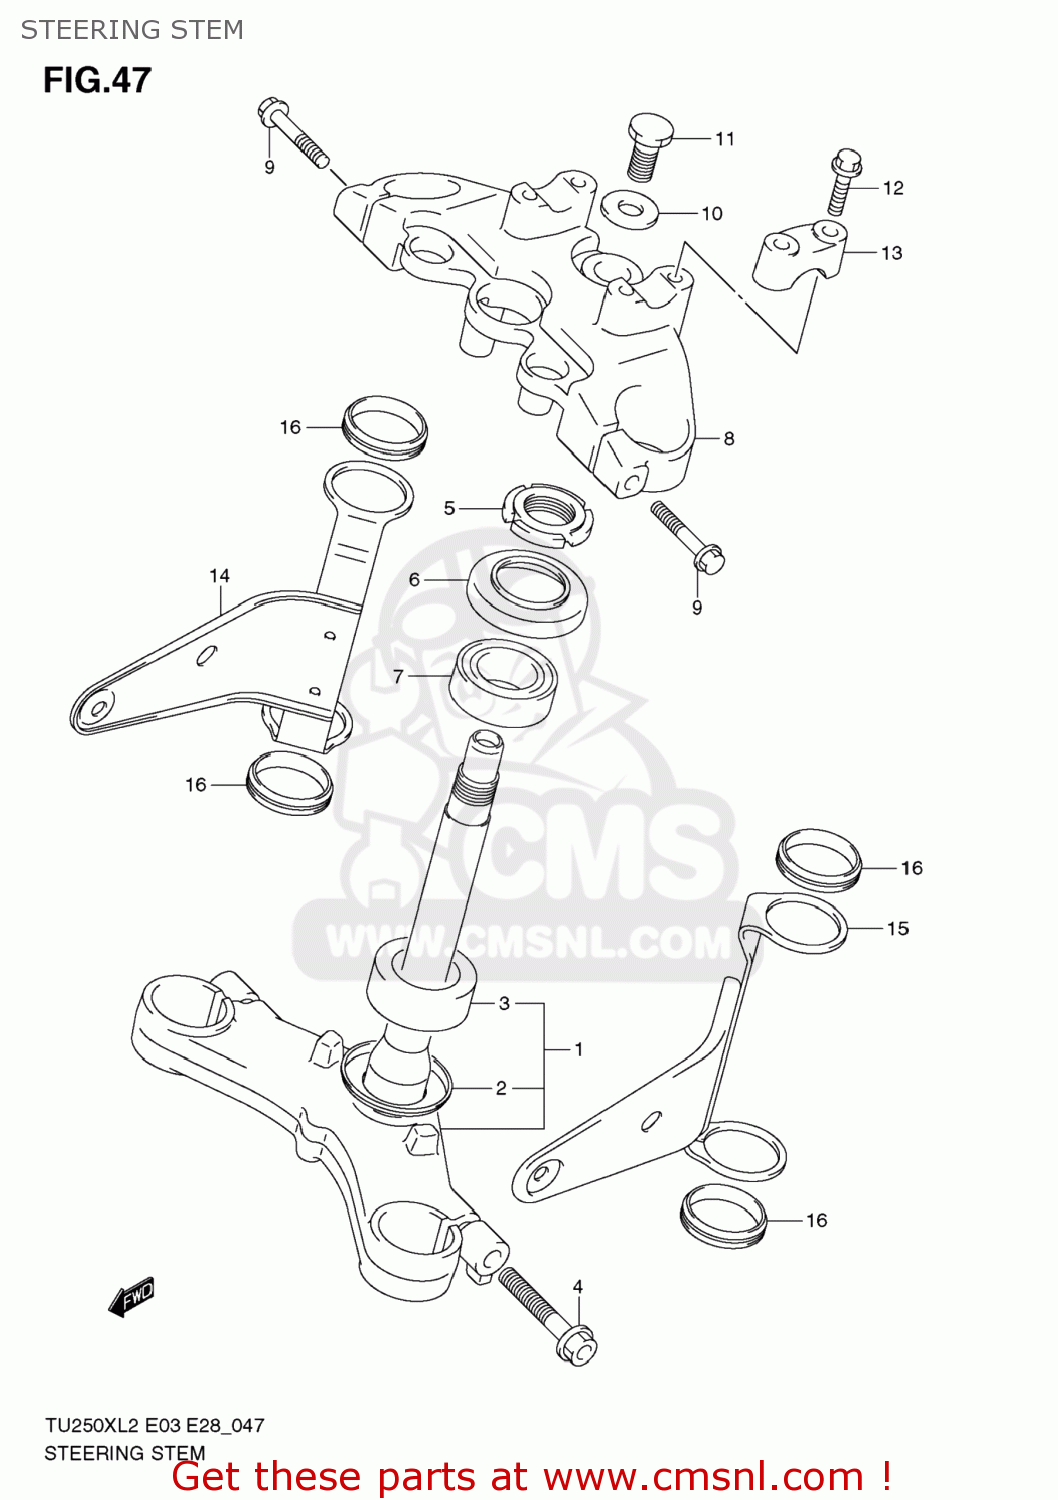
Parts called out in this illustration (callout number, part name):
1	STEM,STEERING
2	SEAL,STEERING LWR
3	BEARING(30X55X17)
4	BOLT
5	NUT,STEERING STEM(25X44X10)
6	SEAL,STEERING UPR DUST
7	BEARING(25X47X15)
8	HEAD,STEERING STEM
9	BOLT
10	WASHER,STEERING STEM
11	BOLT,STEERING STEM HEAD
12	BOLT
13	HOLDER,HANDLE UPR
14	BRACKET,HEADLAMP,R
15	BRACKET,HEADLAMP,L
16	CUSHION,HEADLAMP BRACKET
